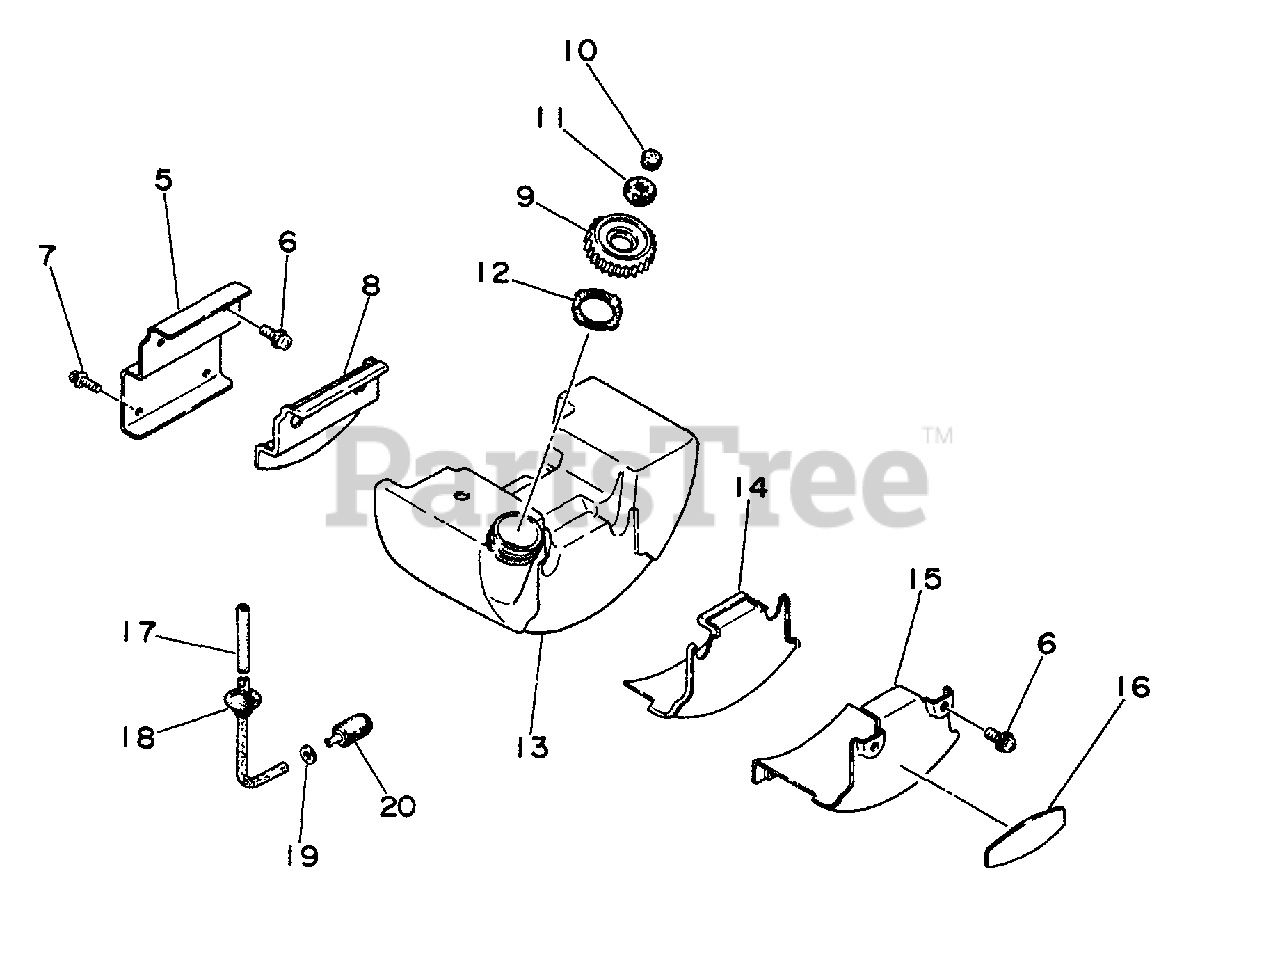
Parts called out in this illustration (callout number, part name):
5	BRACKET, FUEL TANK
6	SCREW - 5X14
7	SCREW - 4X14
8	CUSHION
9	CAP ASSY
12	GASKET, CAP
13	TANK, FUEL
15	BRACKET, FUEL TANK
16	LABEL - ECHO
17	FUEL PIPE KIT
19	WASHER - 5
20	FILTER, FUEL
